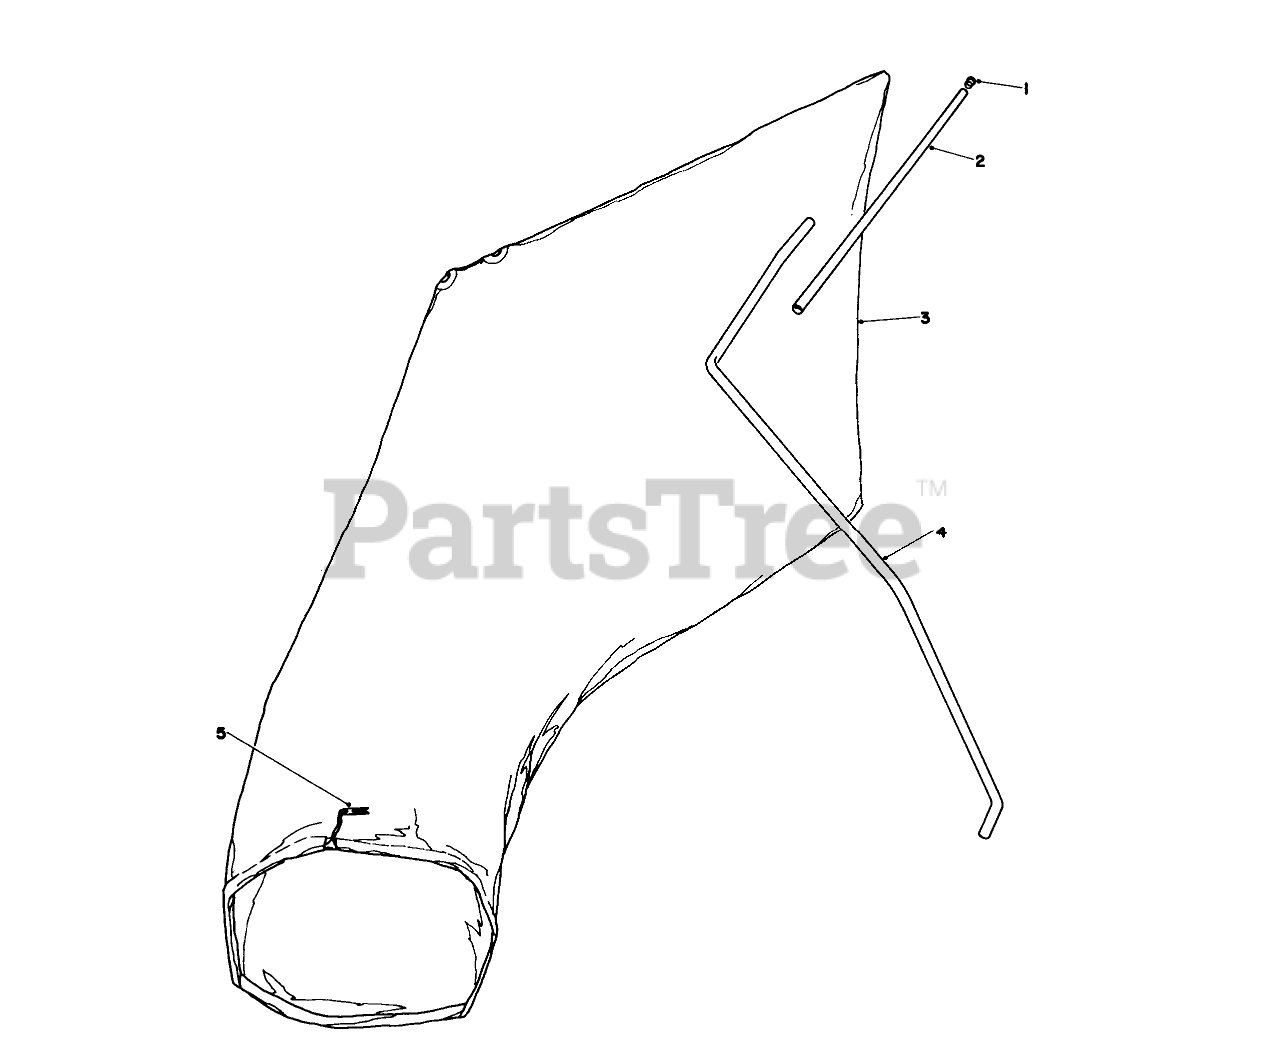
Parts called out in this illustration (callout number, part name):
2	BAG HANGER TUBE
3	Bag (Incl. Ref. #5)
4	HANGER ROD
5	BAG CORD FASTENER
